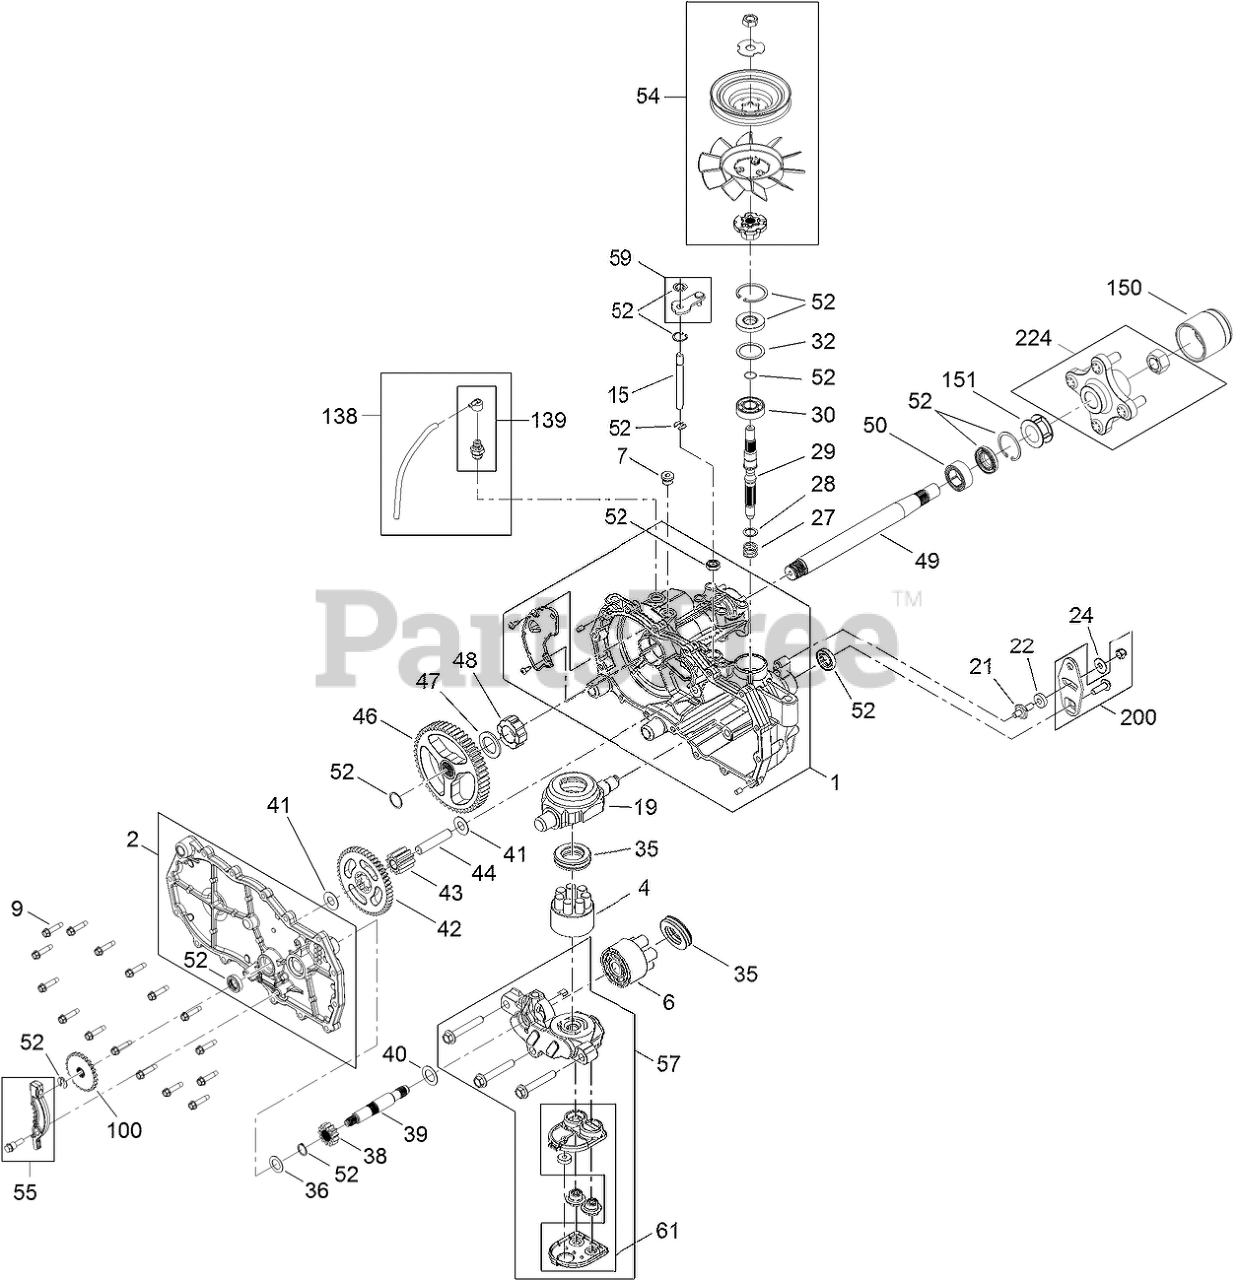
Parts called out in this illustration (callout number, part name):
1	MAIN HOUSING ASM
2	SIDE ASM
4	PUMP BLOCK ASM
6	CYLINDER BLOCK KIT
7	PLUG-THREAD, STRAIGHT
9	SCREW-HHF
15	ROD-BYPASS
19	SWASHPLATE-TRUNNION
22	PUCK-FRICTION
24	WASHER
27	SPRING-COMPRESSION
28	WASHER
29	SHAFT-INPUT
30	BEARING-BALL
32	SPACER
35	BEARING-THRUST
36	WASHER-FLAT
38	GEAR-PINNION, 13T
39	SHAFT-MOTOR
40	WASHER
41	WASHER
42	GEAR-10T/48T
43	GEAR-JACKSHAFT, 10T
44	PIN-JACKSHAFT
46	GEAR-52T, BULL
47	WASHER
48	BEARING-SLEEVE
49	SHAFT-AXLE
50	BUSHING-AXLE
52	SEAL KIT
54	FAN PULLEY KIT
55	BRAKE ARM KIT
57	CENTER SECTION FILTER KIT
59	BYPASS ARM KIT
61	FILTER KIT
100	DISC-BRAKE, COG
138	BREATHER KIT
139	BREATHER ASM
150	CAP-AXLE
151	TUBE-AXLE
200	CONTROL ARM KIT
224	HUB KIT
